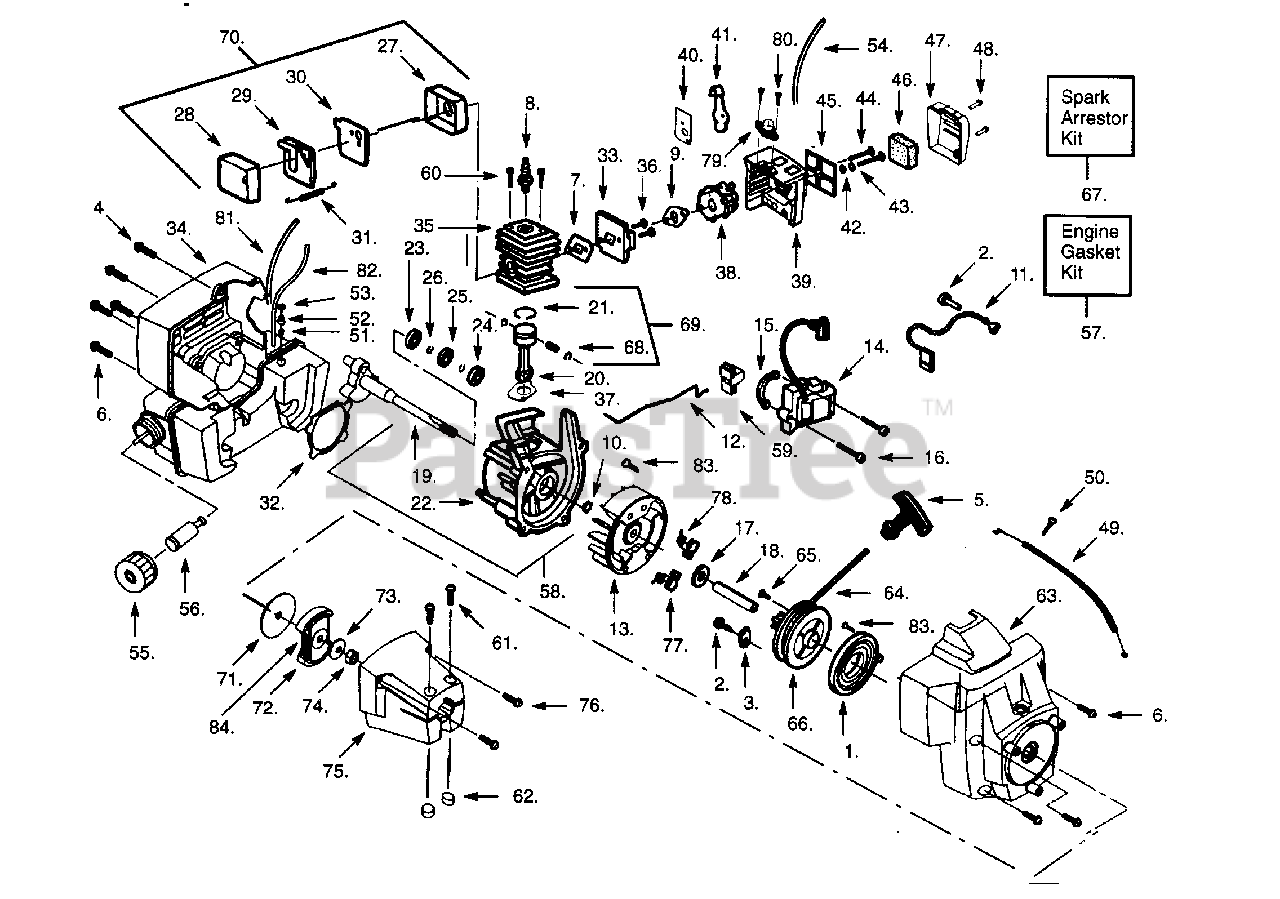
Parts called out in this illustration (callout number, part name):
1	Starter Spring
3	Retainer
5	Starter Handle
6	Screw
7	Cylinder Gasket
8	Spark Plug
10	Retainer
11	Lead Wire
12	Switch Wire Form
13	Flywheel Ass'y.
14	Ignition Module
19	Crankshaft Ass'y.
20	Connecting Rod Ass'y.
21	Piston Ring
22	Crankcase Ass'y.
23	Inner Bearing
24	Outer Bearing
25	C'case Seal
26	Retaining Ring
27	Muffler Body
28	Muffler Cover
29	Muffler Baffle-Exit
30	Muffler Baffle-First
31	Muffler Spring
34	Type 2 & 3
35	Cylinder
38	Type 1 (WT-245)
38	Type 2 & 3(WT-380)
39	Type 2 & 3
40	Choke Plate
41	Choke Shutter
42	Wave Washer
43	Choke Spacer
45	Filter Plate
46	Air Filter Foam
47	Air Filter Cover
49	Throttle Cable Ass'y.
51	Check Valve
53	Retainer
54	Fuel Line-Prim./Carb
55	Fuel Cap Ass'y.
56	Fuel Pickup Ass'y.
57	Engine Gasket Kit (Inc. 7, 9, 32, 37)
58	C'case & C'shaft Assy. (Inc. 10,19,22-26)
59	Switch Button
63	Fan Housing
64	Rope Kit
66	Starter Pulley
67	Spark Arrestor Kit
68	Piston Pin Retainer
69	Piston Kit (Inc. 21,68 & Pin)
70	Muffler Kit
72	Clutch Ass'y.
75	Clutch Hsg.
77	Starter Dog
78	Starter Spring
79	Primer Bulb Ass'y Type 2 & 3
80	Screw-Type 2 & 3
81	Fuel Line-Prim./Tnk
82	Fuel Line-Carb./Tnk.
83	Screw-Flywheel
84	Spring-Clutch
